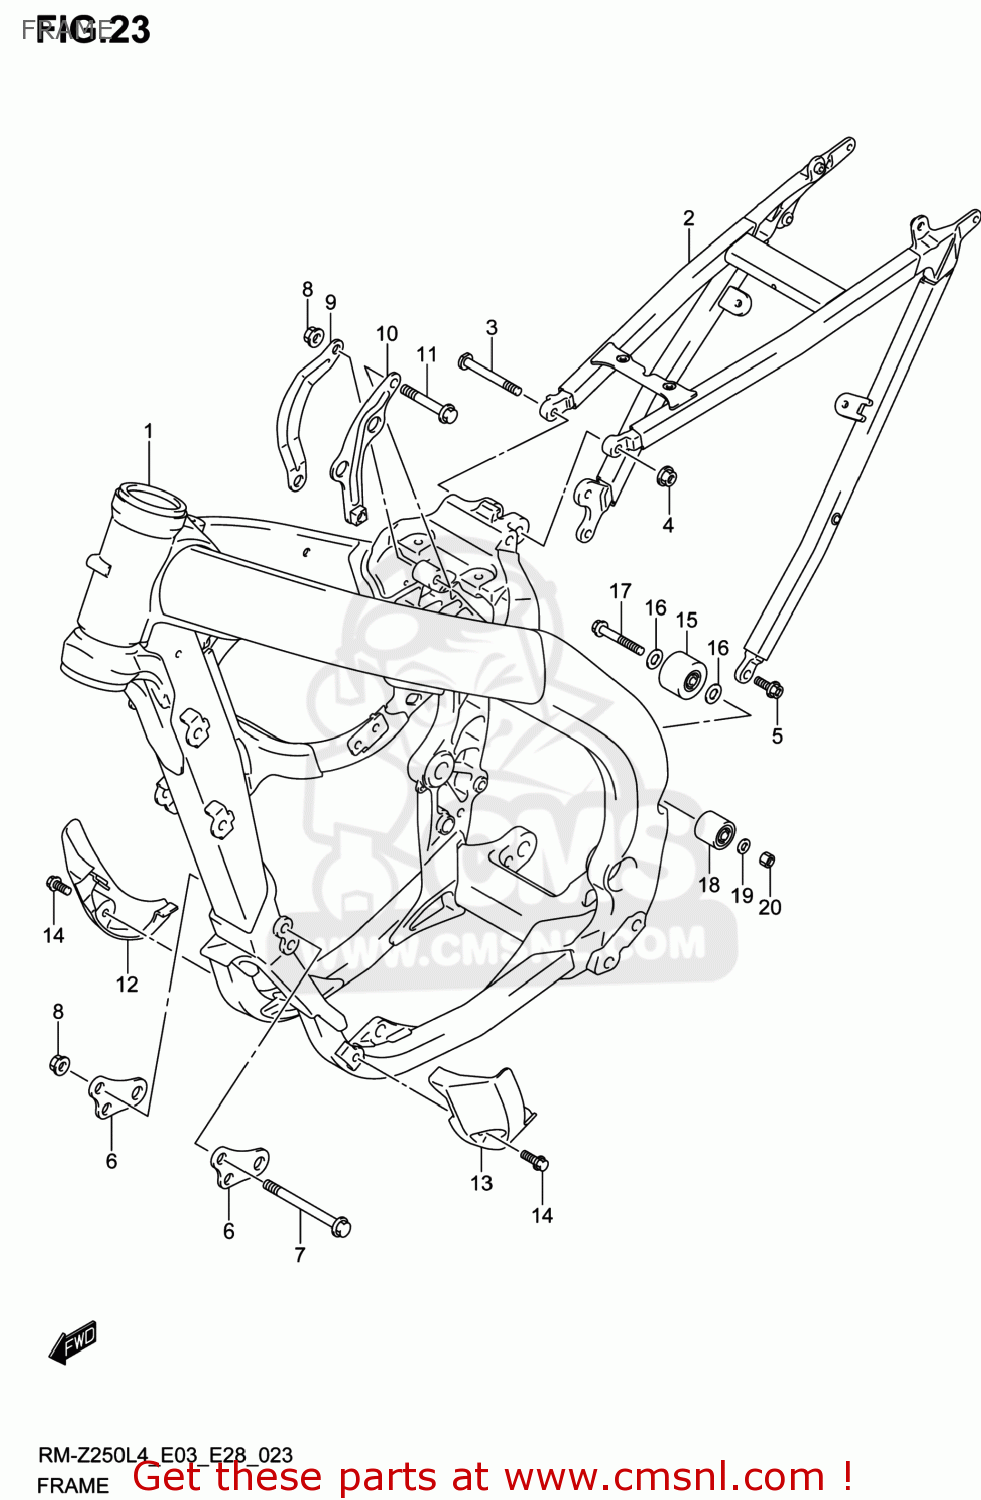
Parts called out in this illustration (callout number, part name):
1	FRAME
2	RAIL,SEAT
3	BOLT,SEAT RAIL UPR
4	NUT
5	BOLT(8X20)
6	BRACKET,ENGINE MOUNTING FR
7	BOLT(8X80)
8	NUT
9	BRACKET,ENGINE MOUNTING UPR,R
10	BRACKET,ENGINE MOUNTING UPR,L
11	BOLT(8X40)
12	PROTECTOR,FR,R
13	PROTECTOR,FR,L
14	BOLT(6X16)
15	ROLLER,CHAIN
16	SHIM(8X16X1)
17	BOLT(8X45)
18	ROLLER,CHAIN
19	SHIM(8X12X1)
20	NUT
